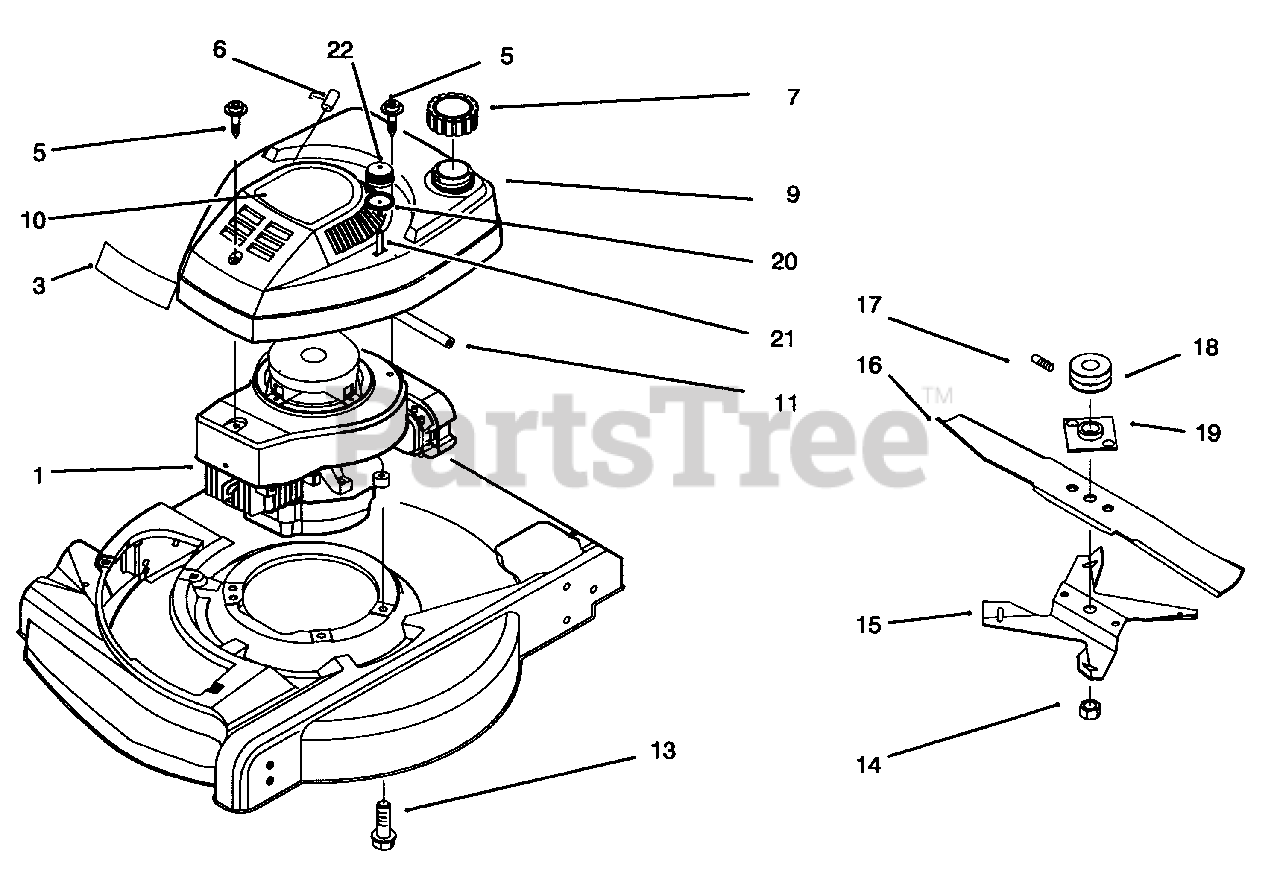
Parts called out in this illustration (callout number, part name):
1	Engine Ass'y-2 Cycle
3	Applique
5	Screw
6	Stop-Rope
7	Cap Assembly-Fuel Includes
9	Shroud & Tank Ass'y
10	Decal-Shroud (Hand Push)
11	Hose-Gas
13	Screw-Engine Mount
14	Nut-Blade
15	Fan-Mulching
16	Blade-21"
17	Screw-Set, Pulley
18	Pulley-Engine
19	Plate & Collar Ass'y
20	Body-Primer
21	Hose-Primer
22	Bulb-Primer
